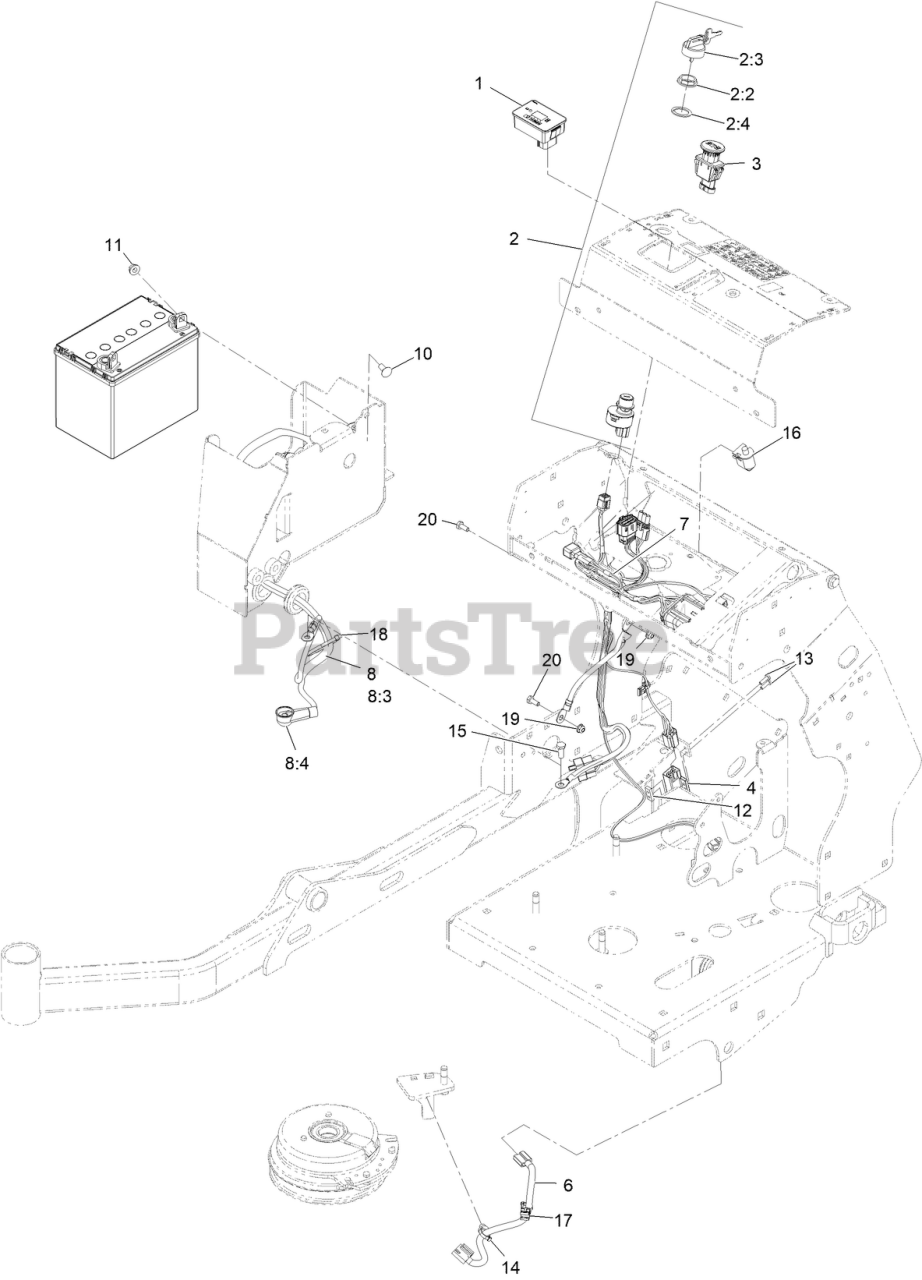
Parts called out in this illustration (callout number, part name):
1	MODULE-HOUR METER
2	IGNITION SWITCH ASM
2:2	NUT-MOUNTING
2:3	IGNITION KEY SET
2:4	WASHER-BACKUP
3	SWITCH-PTO, SEALED
6	HARNESS-CLUTCH PIGTAIL
7	HARNESS-WIRING
8	HARNESS-BATTERY
8:3	Insulator-Lug, Red
8:4	Boot-Battery, Red
10	BOLT-CARR
12	PLATE-TAPPED
13	SCREW-PPH
14	CLIP-TIE
15	SCREW-HH
16	SWITCH-BAIL
17	Clip-Edge
18	TIE-CABLE
20	SCREW-HH
